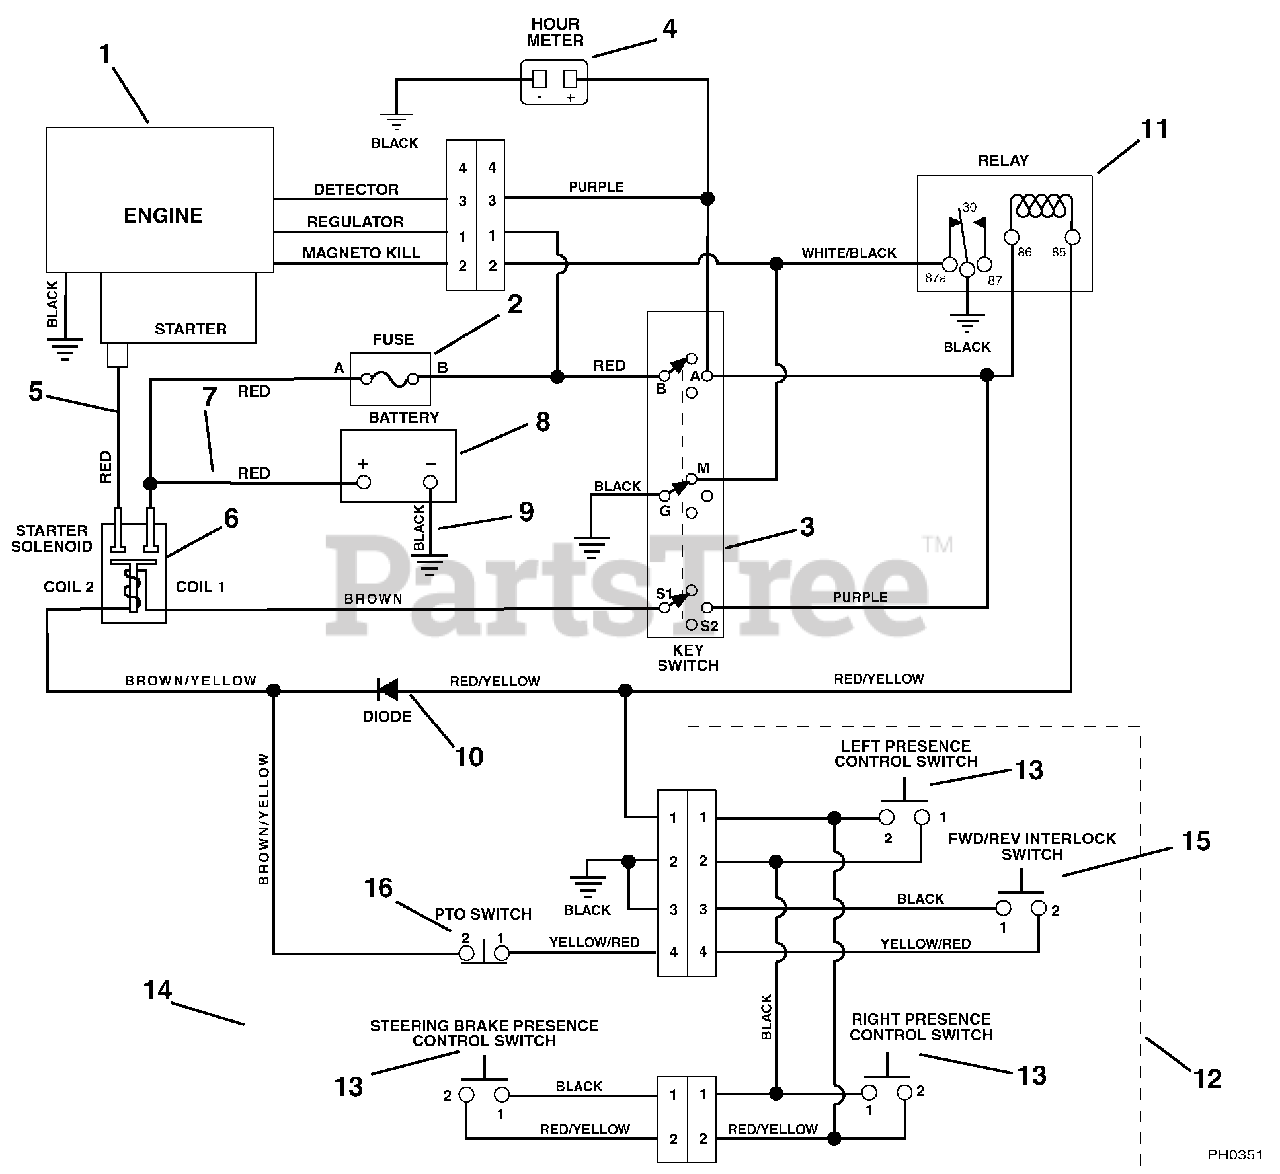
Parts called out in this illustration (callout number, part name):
1	Engine, Robin (115, 307)
1	Engine, Robin (117, 309, 311, 312)
2	Fuse 30 AMP
3	Key Switch
4	Hour Meter
5	Start Cable 22"
6	Solenoid
7	Starter Cable 13" - Battery to Solenoid
8	Battery with Tube (307, 309, 311, 312)
8	Battery (115, 117)
9	Cable, Negative Battery 35"
10	Molded Diode Plug- Clear 1 AMP
11	Relay
12	Harness, Handlebar
13	Switch
14	Harness, Steering Brake
15	Switch, Interlock Closed (Forward/Reverse)
16	Switch, Interlock Open (PTO)
